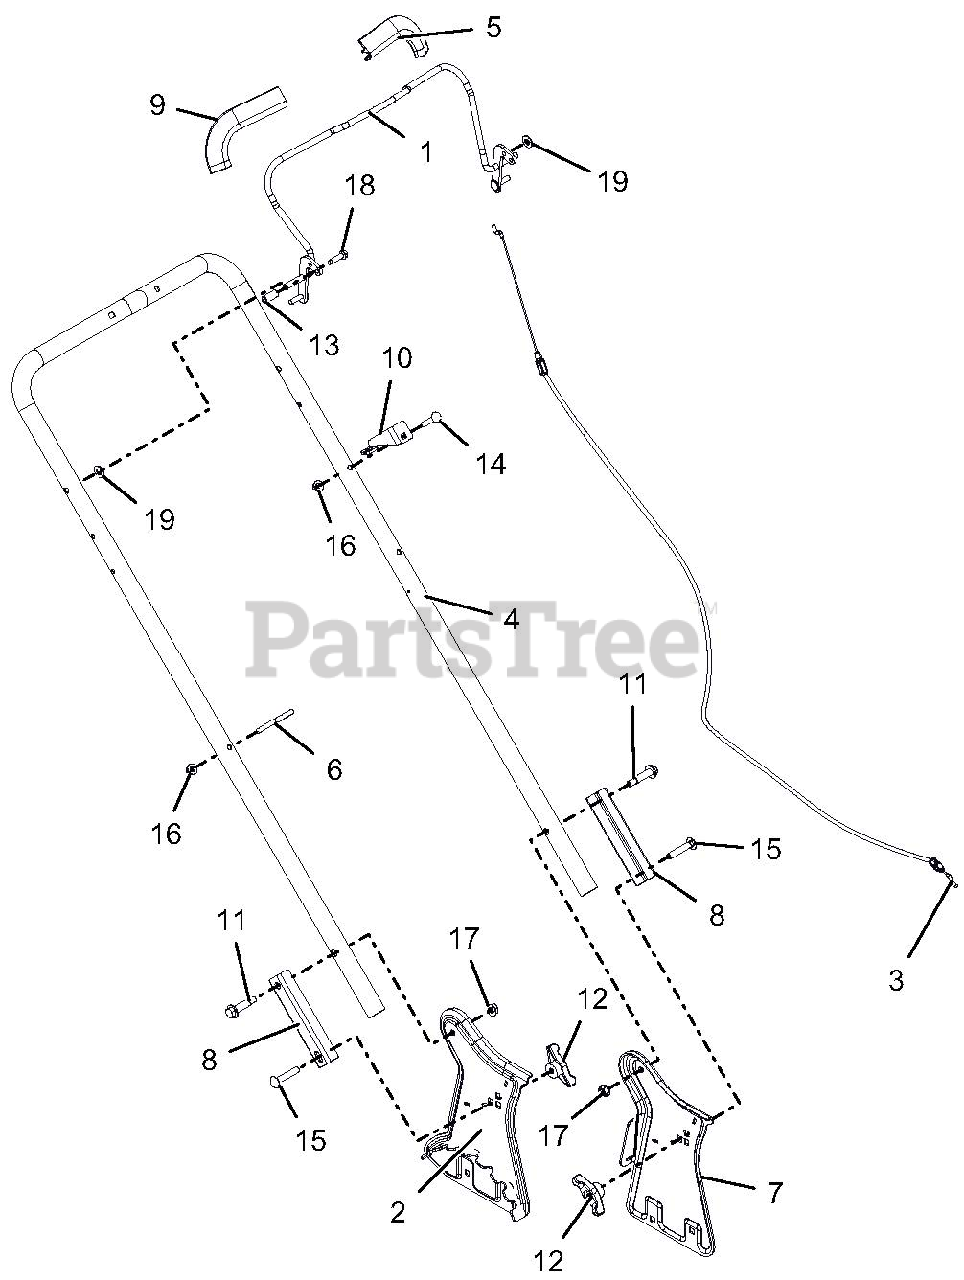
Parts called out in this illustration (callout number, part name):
1	WLDMT, OPC BAIL
2	SUPPORT, RH HANDLBAR
3	CABLE, OPC, RAZOR LM
4	HANDLEBAR, LM
5	GUARD, FINGER - LH
6	HOLDER, RECOIL CORD
7	SUPPORT, LH HANDLEBAR
8	BRKT, HANDLEBAR FIXED ADJUST
9	HAND GRIP W/ DECAL
10	BRKT, CABLE ANCHOR - LM PUSH
11	BLT-SHLDR, .50X1.15X.312-18GR5
12	KNOB,WING .31-18 UNC NYL/TALC
13	CAP, VINYL, .25 ID
14	@BLT-RDHDSQNK .25-20X1.50 G5YZ
15	@BLT-RDHDSQNK .31-18X1.75 G5YZ
16	@NUT-LK-TOP-FLG .25-20 YWZC
17	@NUT-LK-TOP-FLG .31-18 YWZC
18	@SCR-TAP .25-20X1.00 HWH TR YZ
19	@WSHR-FL-STL.344X.688X.065YWZC
